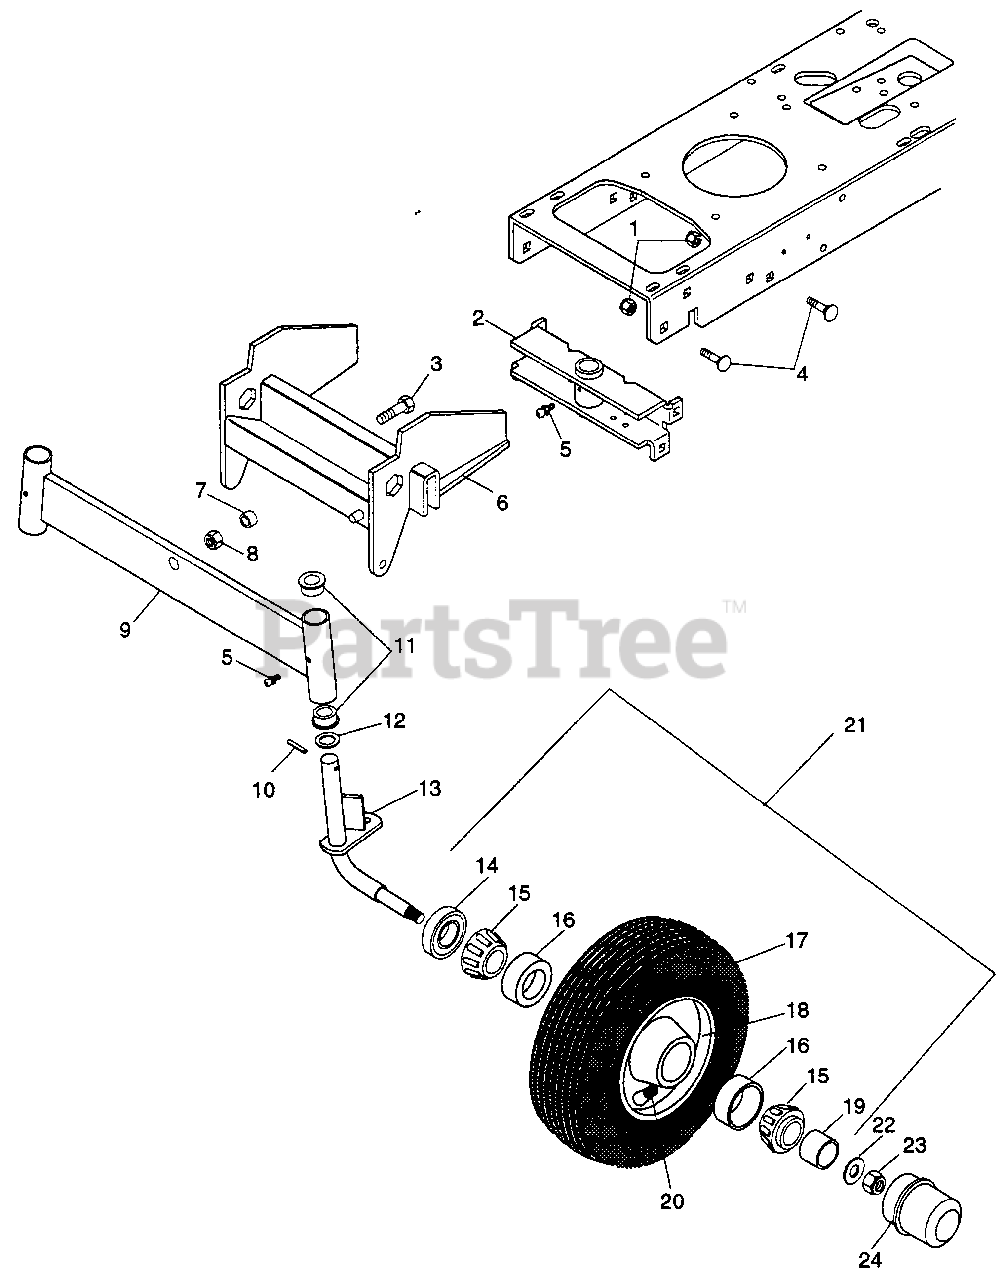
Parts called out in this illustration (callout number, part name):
1	Nut-Lk-Nyl .375-16 Pl
2	Pivot Channel
3	Blt-Hex .50-13 x 1.50 Pl Gr 5
4	Blt-Rdhdsqnk .38-16 x 1.0 Pl
5	Spin Drive Zerk Fitting
6	Front Axle Support
7	Spacer
8	Nut-Lk-Nyl .50-13 Pl
9	Front Axle
10	Scr-Skh .31-18 x 1.00
11	Bshg-Flg 1.000 x 1.25 x .75 x 1.50
12	Wshr-Thrst 1.55 x 1.002 x .093
13	King Pin LH
13	King Pin RH
14	Seal 1.206 x 1.785 x .486
15	Brg-Cone .750 x .61
16	Brg-Cup 1.781 x .475
17	Tire, Front 16 x 6.50-8
18	Weldment, Rim
19	Spacer
20	Valve Stem Ass'y
21	Whl, Asm Front 400 & 800
22	Wshr-Flat .812 x 1.469 x .134
23	Nut-Lk-Nyl .625-11 Pl
24	Dust Cap
